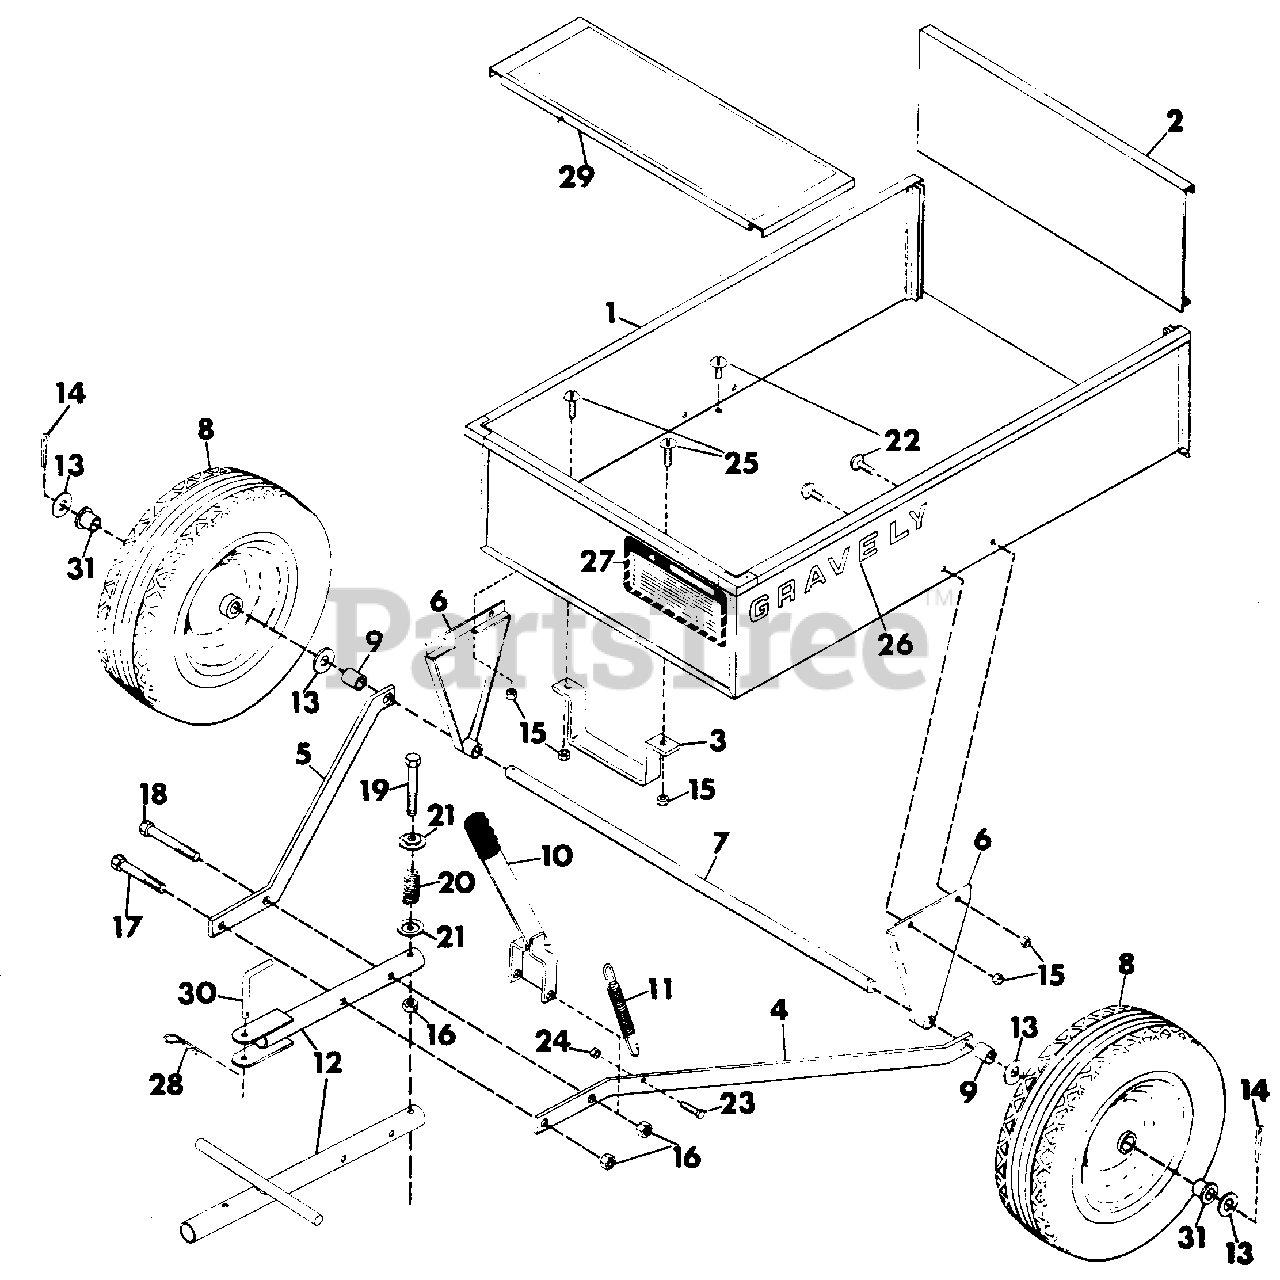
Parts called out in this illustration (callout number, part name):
1	BODY
2	TAILGATE
3	BAR, HITCH
4	BRACE, DRAWBAR L
5	BRACE, DRAWBAR R
6	SUPPORT, AXLE
7	AXLE
8	ASSEMBLY, WHEEL
9	SPACER
10	ASSEMBLY, HANDLE
11	SPRING
12	WELDMENT, TONGUE(4-WHEEL TRACTOR)
12	DRAWBAR(2-WHEEL TRACTOR)
13	WASHER, FLAT 1.062X2.000X.134
14	PIN, COTTER 3/16X1-5/8
15	NUT, HEX 3/8-16
16	NUT, LOCK 1/2-13
17	BOLT, HEX 1/2-13X3.50
18	BOLT, HEX 1/2-13X4.50
19	BOLT, HEX 1/2-13X4.00
20	SPRING, VALVE
21	LOCATOR, VALVE SPRING
22	SCREW, MACH 3/8-16X.75
23	BOLT, HEX 1/4-20X1.00
24	NUT, HEX 1/4-20
25	SCREW, MACH 3/8-16X1.00
26	DECAL, GRAVELY WHITE VINYL
27	DECAL, WARNING
28	PIN, HAIR(4-WHEEL TRACTOR ONLY)
29	SEAT(2-WHEEL TRACTOR ONLY)
30	PIN, HITCH(4-WHEEL TRACTOR)
31	BEARING(2 FOR EACH WHEEL)
